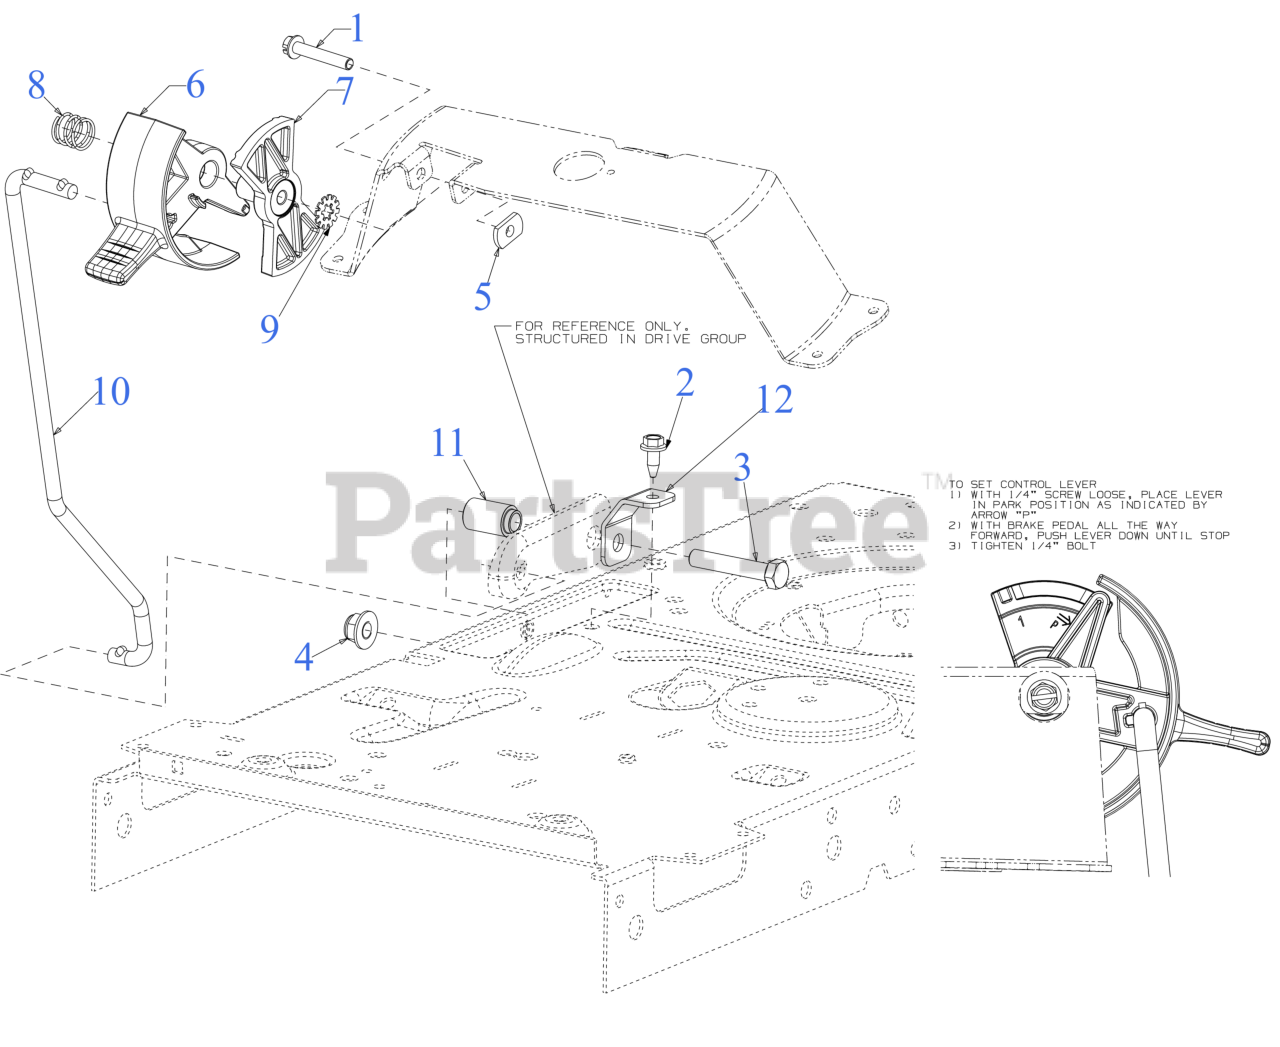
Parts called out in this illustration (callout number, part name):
1	HEX FLANGE BOLT 1/4-20 x 1.5
2	SCREW 1/4-20X.625
3	SCREW 3/8-16 x 2.0 GR 8
5	FLAT NUT
6	SHIFT LEVER
7	PARK INDEX CONTROL
8	COMPRESSION SPRING
9	WASHER
10	SPEED CONTROL ROD
11	FLANGE SPACER
12	SPEED LATCH TAB
